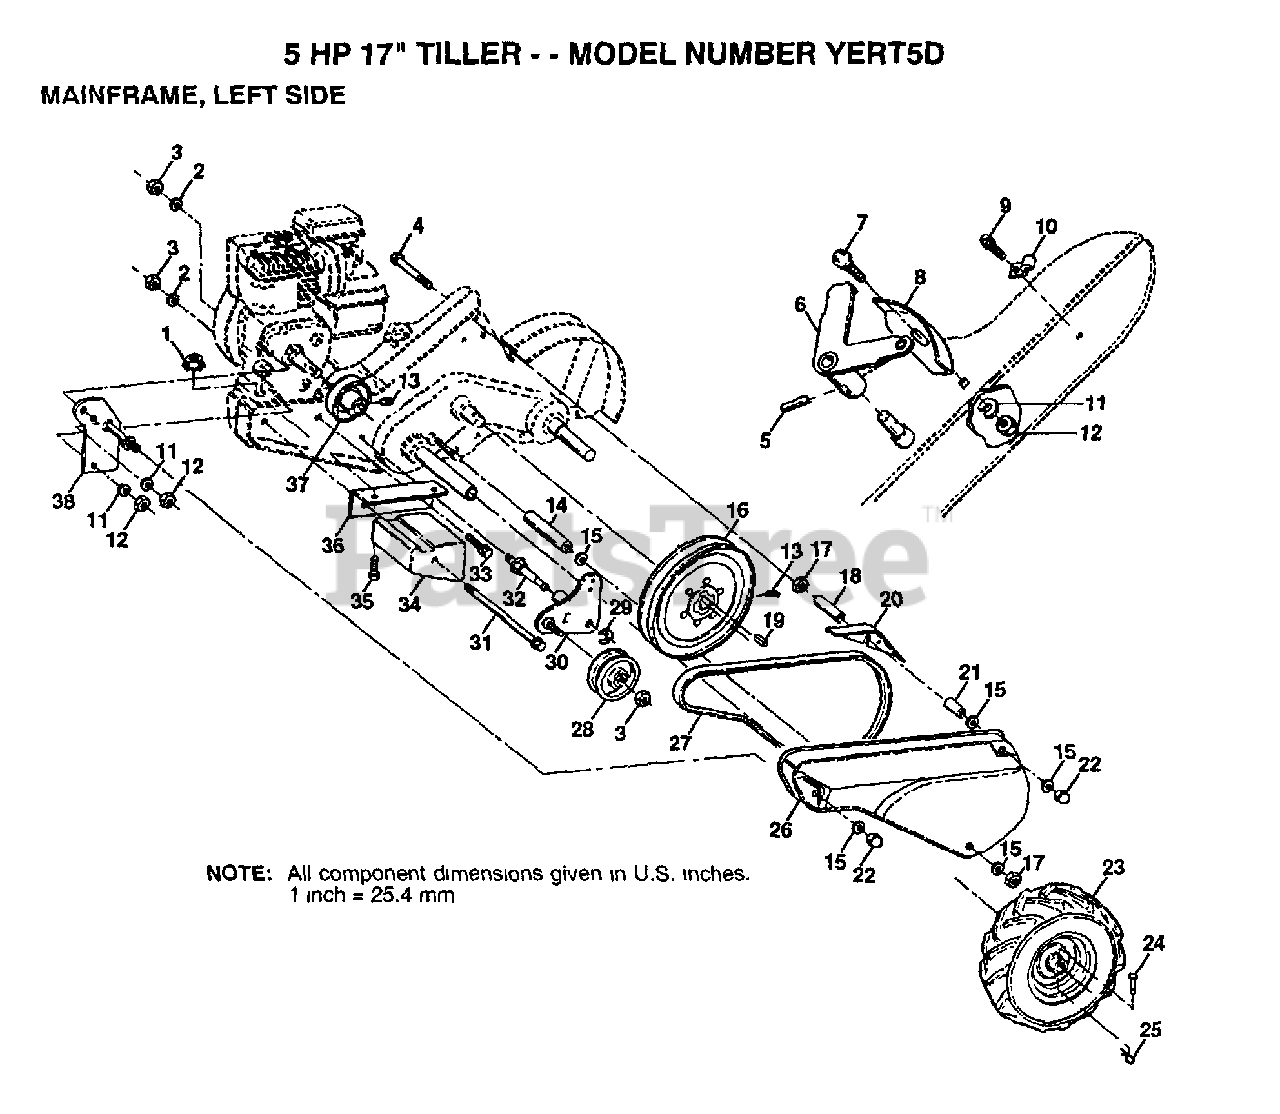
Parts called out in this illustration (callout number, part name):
2	LOCKWASHER
3	NUT.HEX.3/8-16UNC
4	BOLT TI
6	LEVER ASM CRT
7	BOLT
8	PANEL TI
10	CONDIUT CLIP T
11	LOCKWASHER
13	SET SCREW
14	SPACER
15	WASHER
16	"SHEAVE 10"" CRT"
17	NUT.HEX.5/16-18
18	SPACER CRT
19	KEY T
20	GUARD CRT
21	SPLIT SPACER
22	NUT TI
23	TIRE.CHV.13X5.0-6
24	RIVET.DRILL.1.75
25	RETAINER M
27	BELT-V
28	PULLEY-IDLER TI
29	KLIP RING
31	BOLT CRT
32	SHIFT ARM CRT
33	BOLT
34	COUNTERWEIGHT CRT
35	BOLT.HEX.5/16-1.5
36	BRACKET LH CRT
37	ENGINE SHEAVE
38	BELT GUARD BRKT
